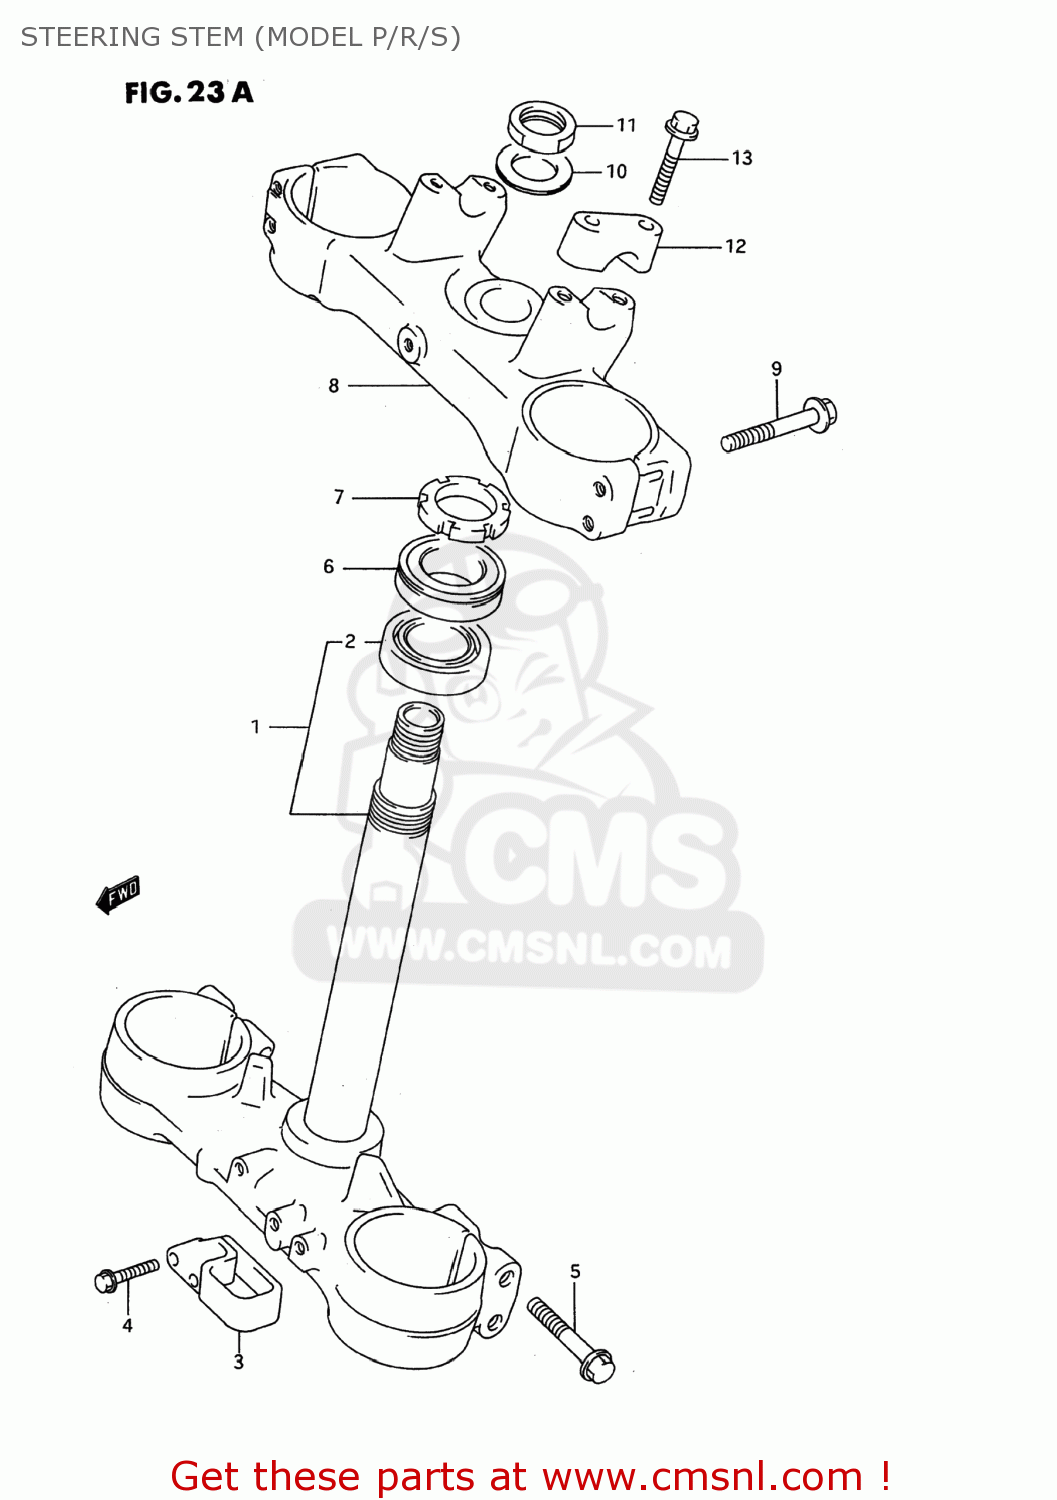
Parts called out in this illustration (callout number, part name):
1	STEM,STEERING
2	BEARING(30X52X16)
3	GUIDE,HOSE
4	BOLT,GUIDE
5	BOLT,STEM 8X45
6	BEARING(30X52X16)
7	NUT,STEERING
8	HEAD,STEERING STEM
9	BOLT,STEM 8X45
10	WASHER,STEM HEAD
11	NUT,STEM HEAD
12	HOLDER,HANDLEBAR
13	BOLT,HANDLE HOLDER(8X35)
